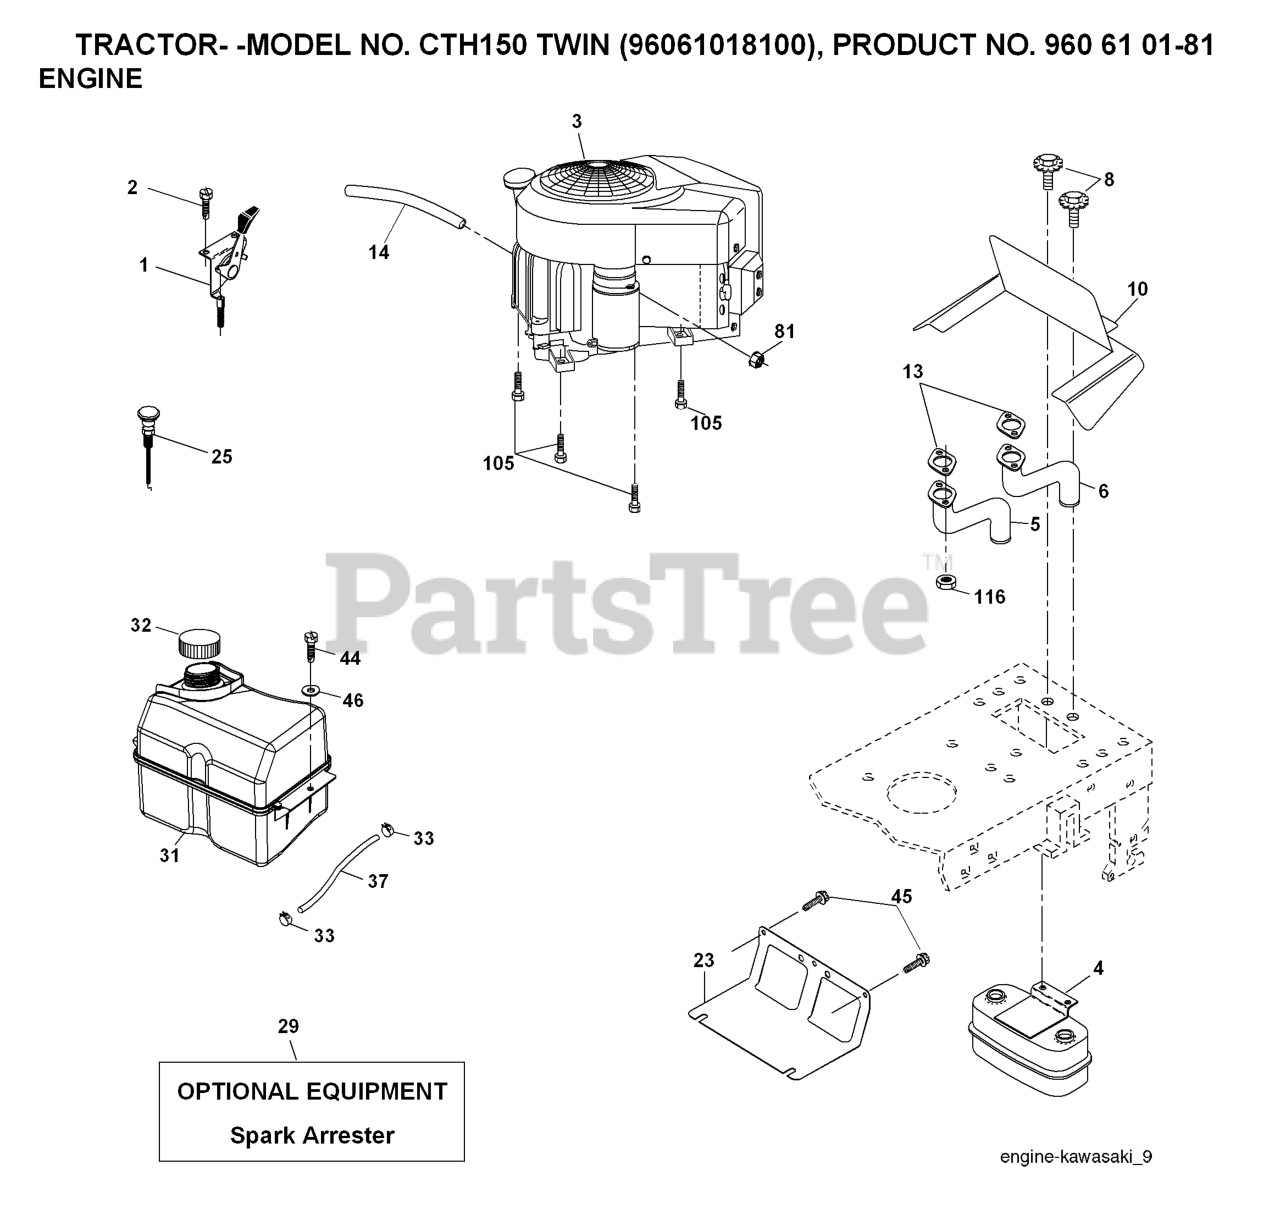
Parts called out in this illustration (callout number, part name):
1	THROTTLE CABLE
2	SCREW
4	MUFFLER.TWIN.CYL.LOW.TONE
5	EXHAUST TUBE LH KAWI
6	EXHAUST TUBE RH KAWI
8	BOLT.5/16-18UNCX3/4 W/SEMS.BLK
10	RP SHIELD HEAT MUFFLER
14	TUBE, DRAIN OIL ASM.
23	SHIELD.BROWNING.DBR.GUARD
25	CONTROL, CHOKE
29	KIT.SPARK ARRESTOR 794945 B&S
31	TANK FUEL
32	FUEL CAP
33	HOSE CLAMP
37	LINE.FUEL.20
44	SCREW HEXWSHR 1/4-20X3/4
45	SCREW, 3/8-16X3/4
81	NUT
105	SCREW 3/8-16X1
116	NUT.HEX.FLANGE.TOPLOCK
119	LENKRAD
120	GUARD 532199767
122	SCREW.1/4-20X5/8
123	SCREW, 5/16-18 X 1/2
